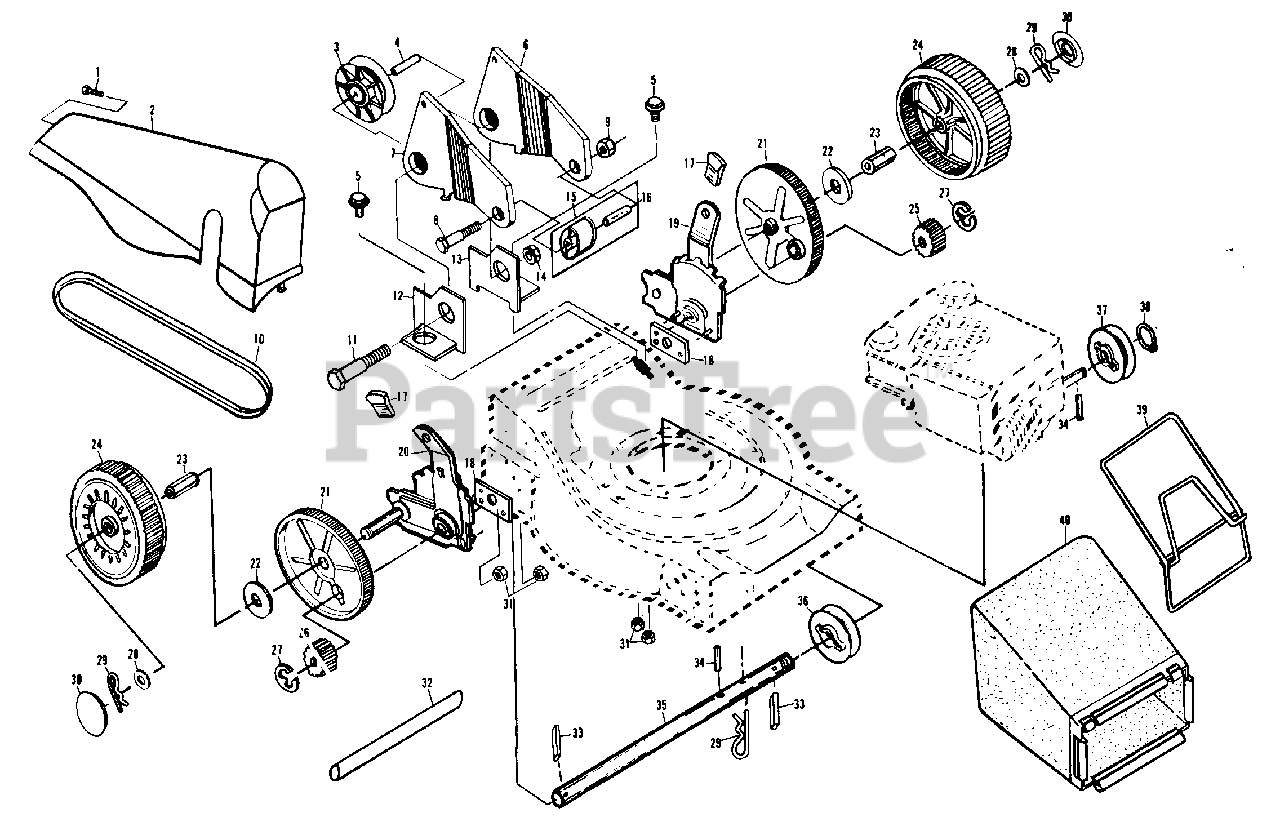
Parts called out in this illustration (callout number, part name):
1	Hex Washer Head Screw (AYP part number)
2	Drive Cover (AYP part number)
3	Idler Pulley (AYP part number)
4	Pulley Spacer (AYP part number)
5	Hex Head Machine Screw (AYP part number)
6	Idler Bracket (Left) (AYP part number)
7	Idler Bracket (Right) (AYP part number)
8	Hex Head Bolt (AYP part number)
9	Hex Locknut (AYP part number)
10	Drive Belt
11	Hex Head Bolt (AYP part number)
12	Pivot Bracket (Right) (AYP part number)
13	Pivot Bracket (Left) (AYP part number)
14	Locknut (AYP part number)
15	Idler Assembly Kit (Inc. 16) (AYP part number)
16	Idler Spacer (AYP part number)
17	Selector Knob (AYP part number)
18	Spacer Plate (AYP part number)
19	Selector Assembly (Left) (AYP part number)
20	Selector Assembly (Right) (AYP part number)
21	Dust Cover
22	Washer (AYP part number)
23	Wheel Bushing (AYP part number)
24	Wheel & Tire Assembly (AYP part number)
25	Drive Pinion (Left) (AYP part number)
26	Drive Pinion (Right) (AYP part number)
27	E-Ring (AYP part number)
28	Flat Washer (AYP part number)
29	Retainer Clip (AYP part number)
30	Hubcap (AYP part number)
31	Locknut (AYP part number)
32	Drive Shaft Cover (AYP part number)
33	Drive Pawl (AYP part number)
34	Roll Pin (AYP part number)
35	Drive Shaft (AYP part number)
36	Driven Pulley (AYP part number)
37	Drive Pulley
38	Retaining Ring (AYP part number)
39	Catcher Frame
40	Grass Bag Assembly
